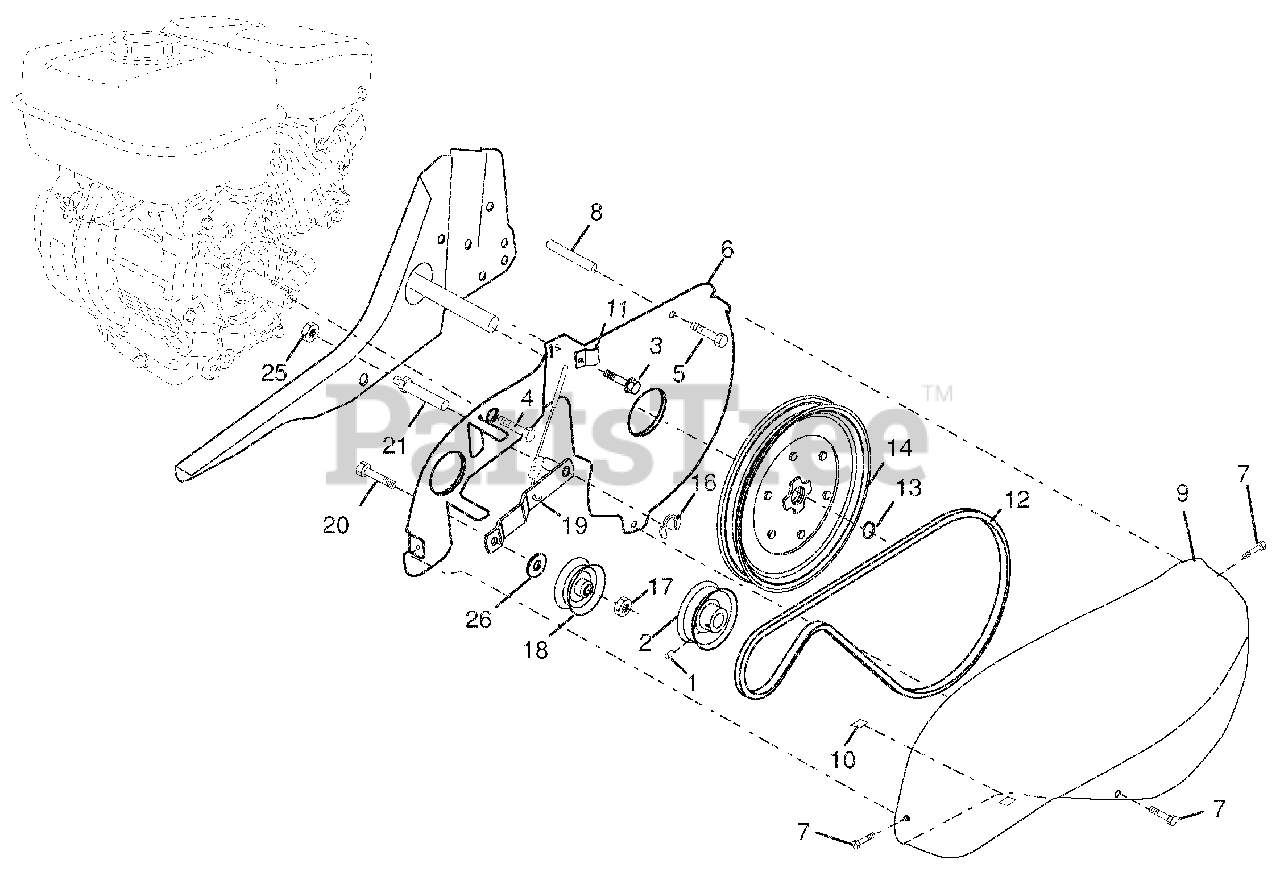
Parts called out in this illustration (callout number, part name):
1	Screw Set 5/16-18 x 3/8 Patch
2	Sheave, Engine
3	Screw, Self-Tapping
4	Bolt, Hex Head 5/16-24 unf x 1
5	Bolt, Thd Roller 1/4-20 x 2-1/
6	Shield, Inner Belt Guard
7	Screw Hex Wsh Hd #8-18 x 1/2
8	Spacer Split
9	GUARD, BELT
10	Pad, Idler
11	Clip, Cable
13	Ring, Retainer
14	Sheave, Transmisison
16	Ring, Klip
17	Nut, Hex
18	PULLEY, IDLER
19	ARM, IDLER
20	BOLT, 5/16-18 X 1 1/2
21	Shaft, Idler Arm
25	Nut, Hex, Jam 5/16-18
26	WASHER, FLAT
